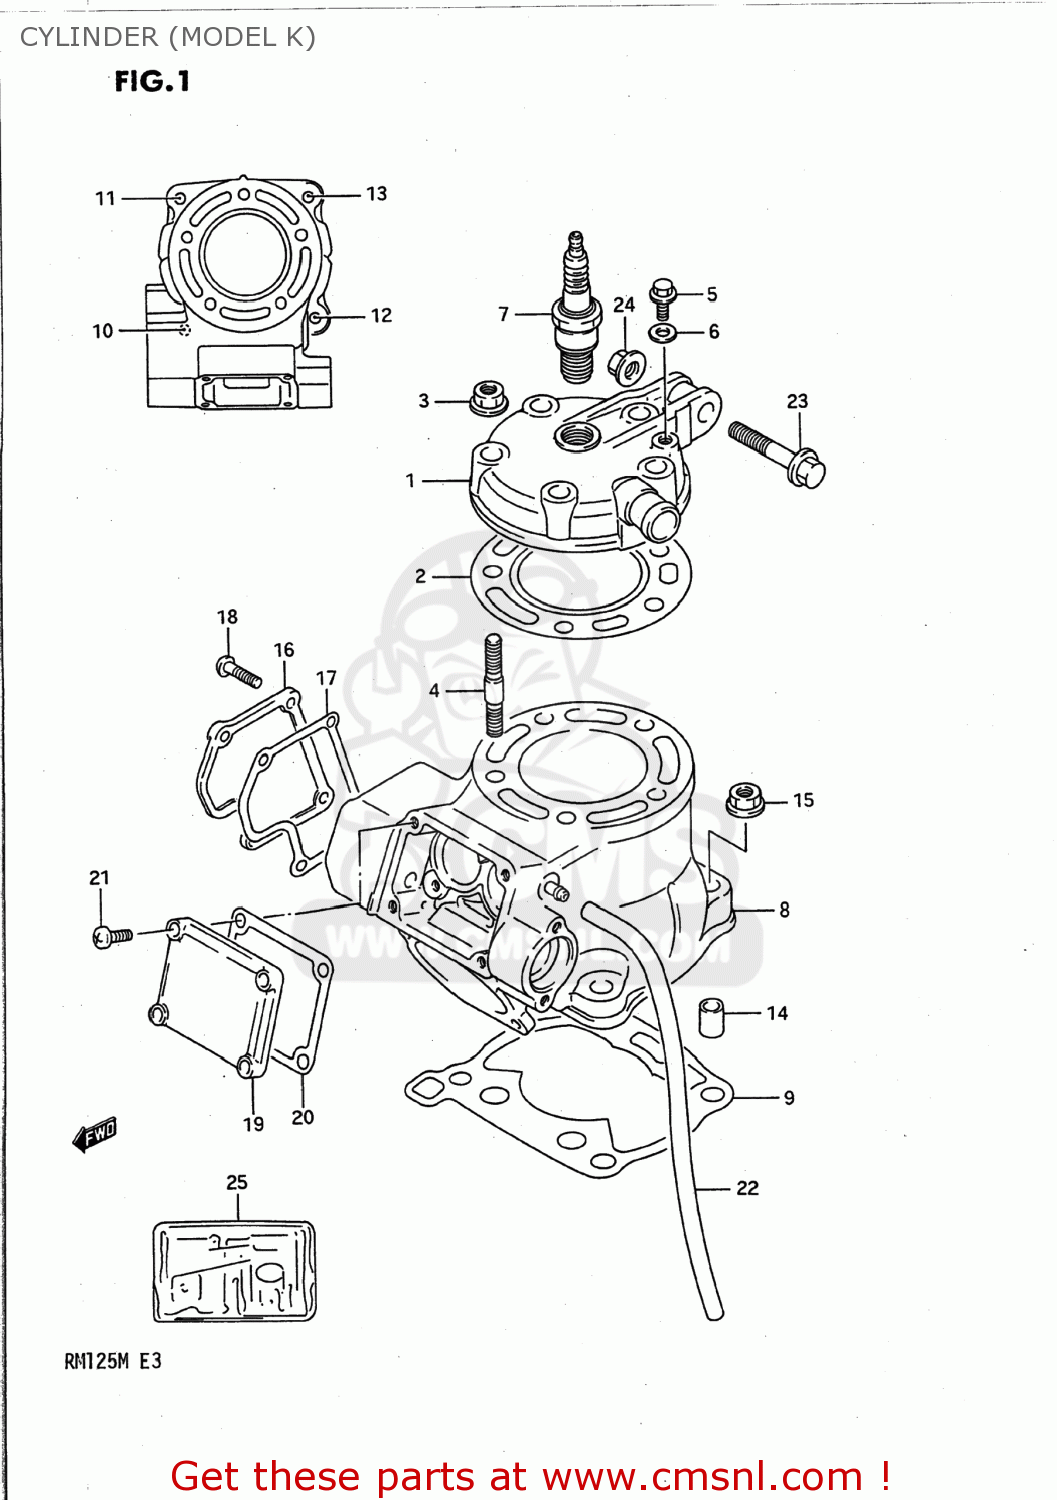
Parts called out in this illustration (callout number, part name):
1	HEAD,CYLINDER
2	GASKET,CYLINDER HEAD (NAS)
3	NUT
4	BOLT,STUD
5	UNION
6	GASKET(6.2X11X1).2 (NAS)
7	SPARK PLUG W27ES-ZU
8	CYLINDER
9	GASKET,CYLINDER (MCA)
10	STUD 8X25
11	BOLT,STUD
12	STUD BOLT
13	BOLT,STUD
14	PIN
15	NUT
16	COVER,CYLINDER NO.1
17	GASKET,CYLINDER COVER (MCA)
18	SCREW
19	COVER,CYLINDER
20	GASKET,CYL COVER NO.2 (NAS)
21	SCREW
22	HOSE(4X7X600)
23	BOLT (8X40)
24	NUT
25	GASKET SET
